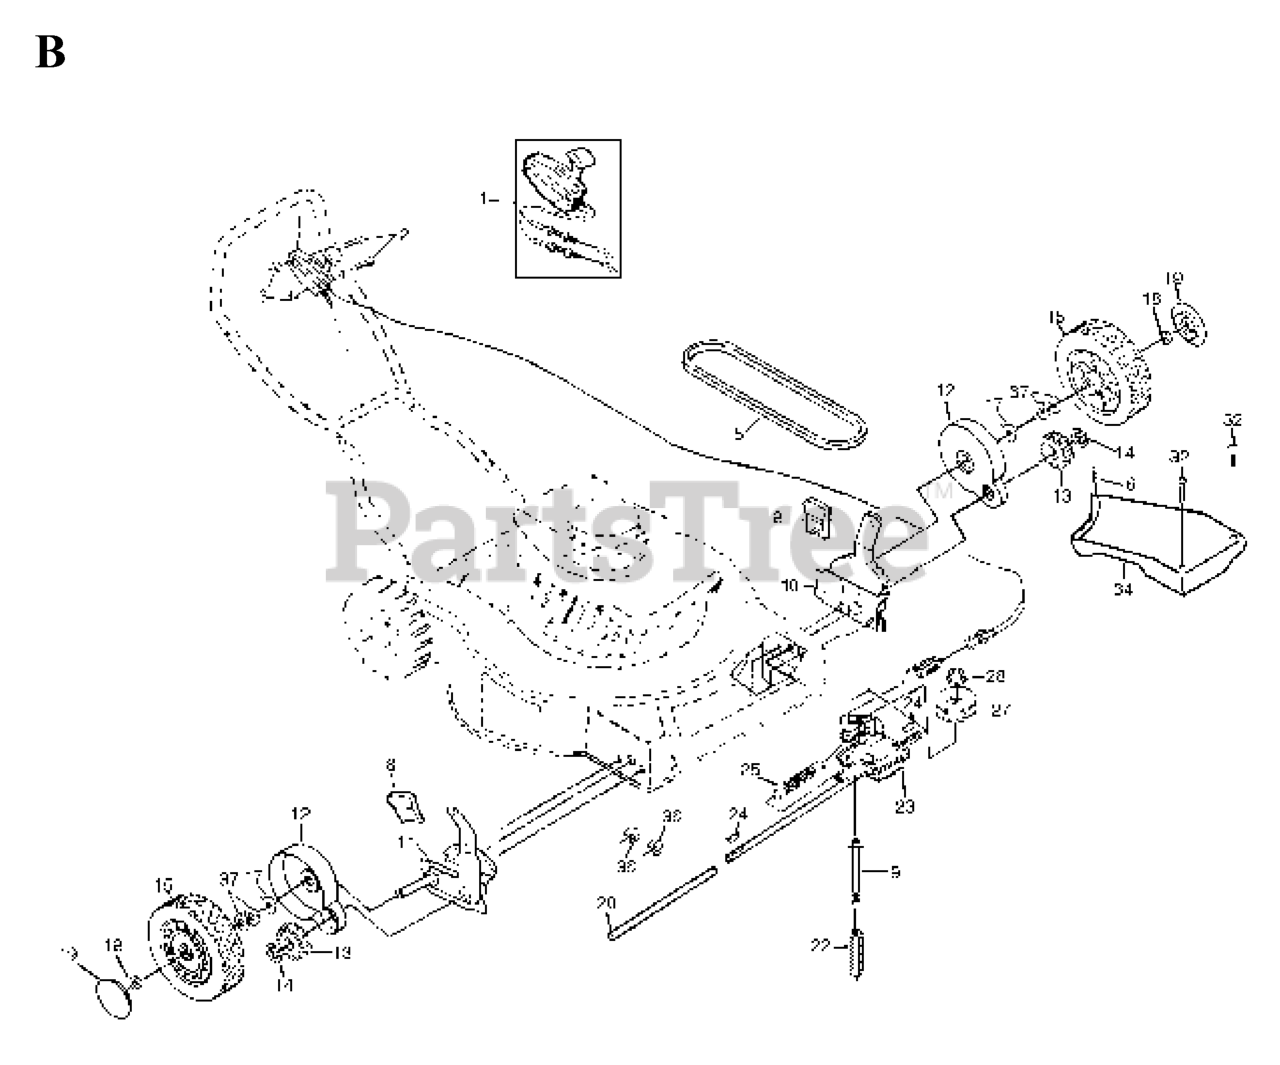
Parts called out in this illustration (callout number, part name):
1	DRIVE CONTROL
2	SCREW 1/4-20 X 2.12
3	NUT
5	BELT THERM .32
6	TAPPING SCREW
8	SELECTOR KNOB
9	SPRING RETAINER
10	WHEEL ADJUSTER ASSY (LEFT)
11	WHEEL ADJUSTER KIT RH
12	DUST SHROUD PM
13	PINION GEAR
14	E-RING 7/16 RE
15	WHEEL & TIRE 8 X 2
17	WASHER FLUT
18	HEX FLANGE LOCKNT
20	DRV SHAFT TUBE PM
22	SPRING.EXTENSION
23	RP.GEAR HOUSING
24	HI PRO KEY
27	PULLEY
28	FLANGED LOCKNUT 3/8-16 ZINC
34	COVER DRIVE
36	NUT
37	WAVE WASHER
